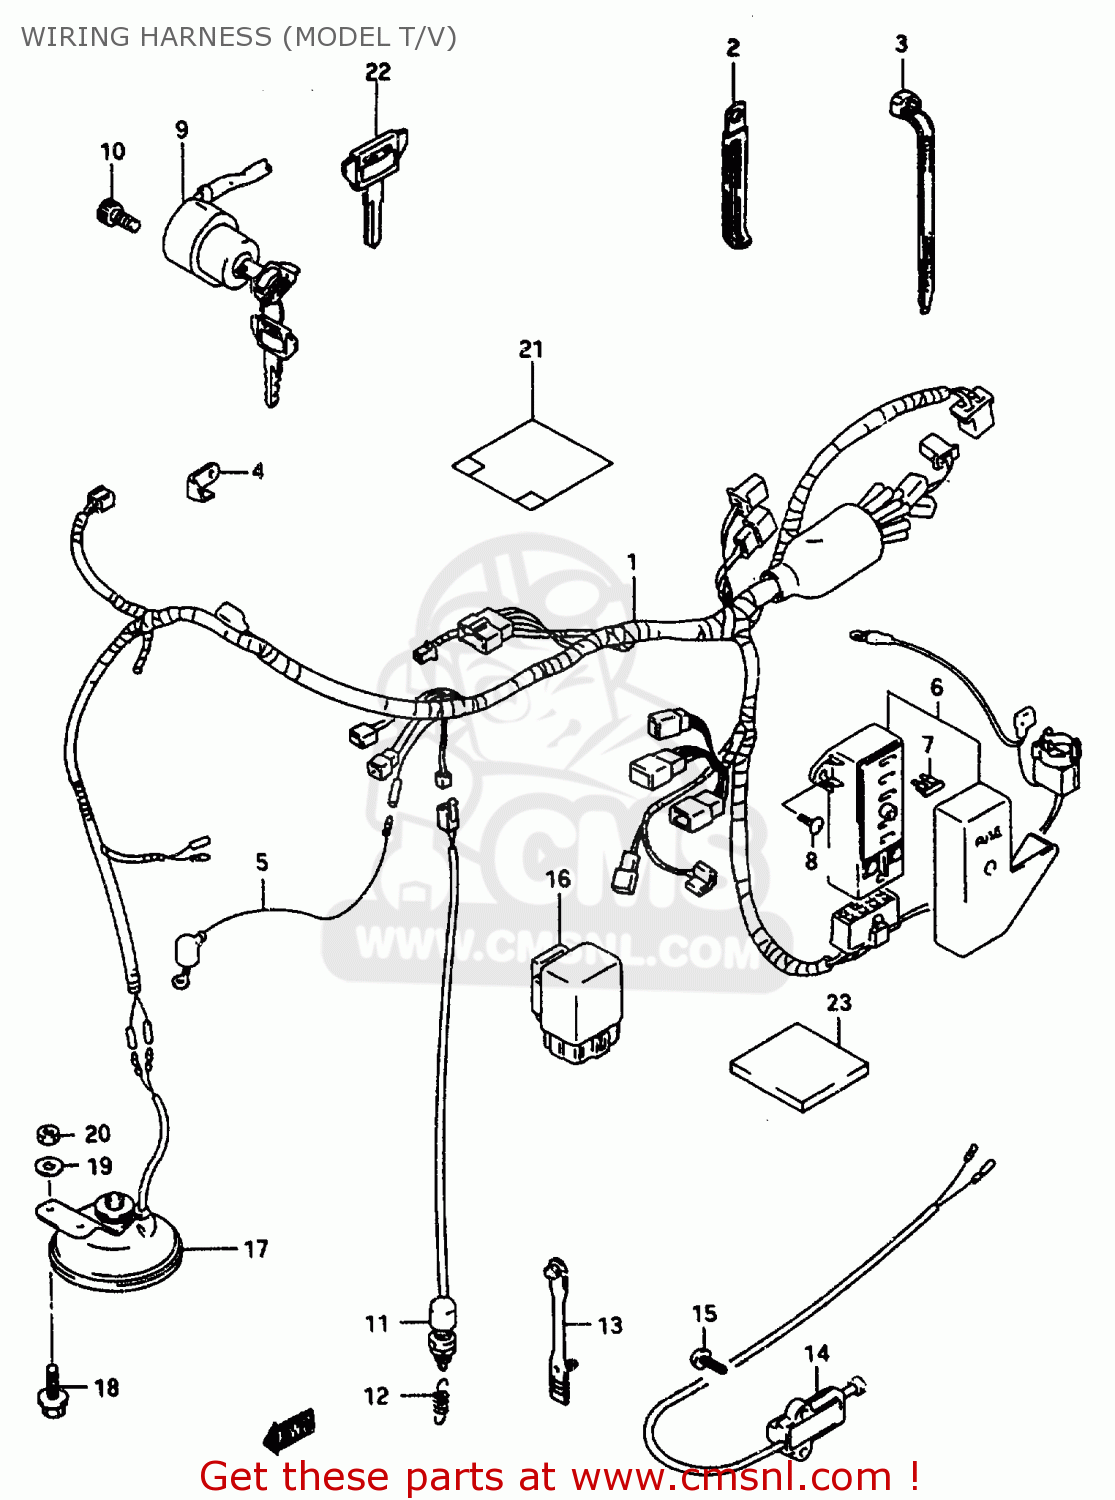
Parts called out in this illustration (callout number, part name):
1	HARNESS,WIRING
2	CLAMP(L:45)
3	CLAMP(L:95)
4	PLATE,COUPLER HOLDER
5	WIRE,WATER TEMP GAUGE LEAD
6	BOX ASSY,FUSE
7	FUSE(10A)
8	SCREW
9	SWITCH ASSEMBLY,IGNITION
10	BOLT
11	SWITCH ASSY,STOP LAMP
12	SPRING
13	CLAMP,L:88
14	SWITCH ASSY,SIDE STAND
15	SCREW
16	RELAY ASSY
17	HORN ASSY
18	BOLT
19	WASHER
20	NUT 6MM
21	COVER,WIRING HARNESS
22	KEY,BLANK(TYPE:C)
23	COVER,HARNESS
24	KEY,BLANK(TYPE:F)
